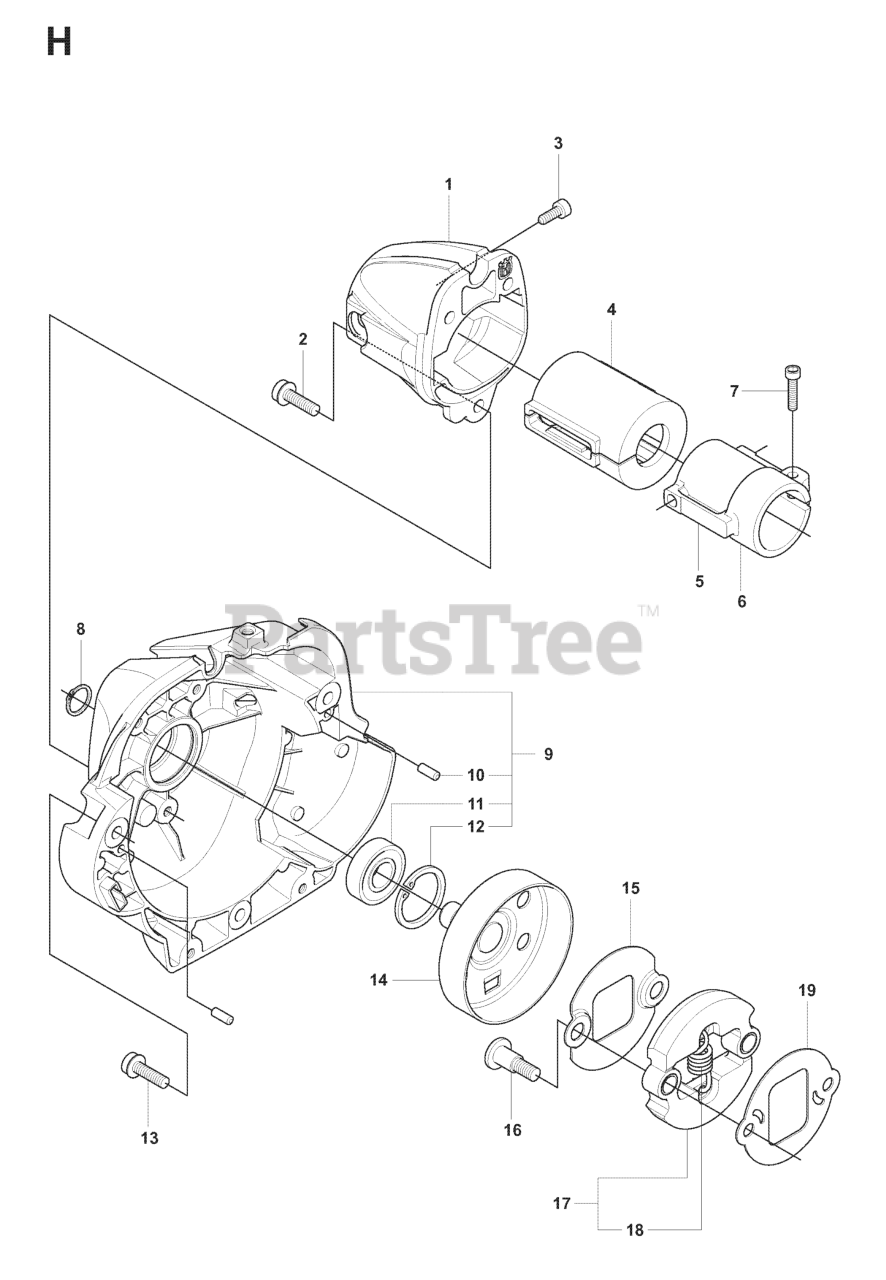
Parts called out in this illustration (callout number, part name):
2	SCREW IHSCFM
3	SCREW IHSCT
4	VIBRATION ABSORBER
5	SLEEVE, COVER
6	LOCKING SLEEVE
7	SCREW MC6S 5X25
8	SEEGER CLIP
9	CLUTCH COVER KPL
11	BALL BEARING
12	RETAINING RING SGH 28
13	SCREW IHSCFM
14	CLUTCH DRUM
16	SCREW CLUTCH
17	CLUTCH CPL
19	WASHER
